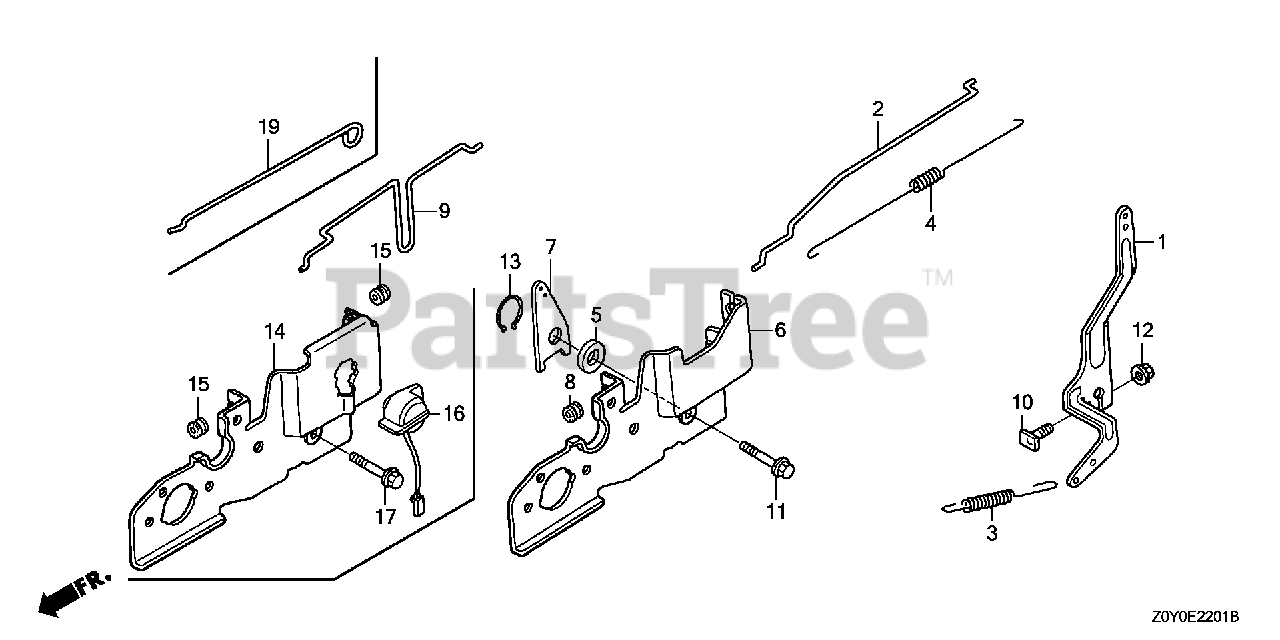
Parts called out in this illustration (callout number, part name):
1	ARM, GOVERNOR
2	ROD, GOVERNOR
3	SPRING, GOVERNOR
4	SPRING, THROTTLE RETURN
5	SPACER, CONTROL LEVER
6	BASE, CONTROL
7	LEVER, CHOKE
8	GROMMET, CHOKE ROD
9	ROD, CHOKE
10	BOLT, GOVERNOR ARM
11	BOLT, FLANGE (6X45) (CT200)
12	NUT, FLANGE (6MM)
13	CIRCLIP (OUTER) (14MM)
